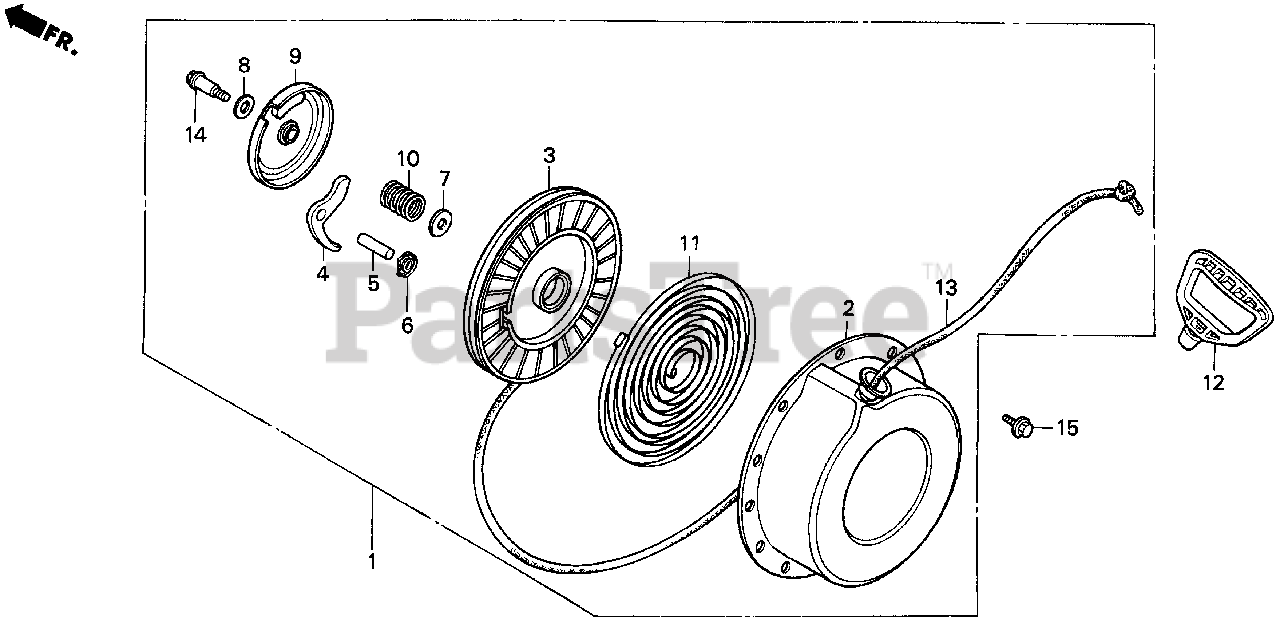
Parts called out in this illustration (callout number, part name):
1	STARTER ASSY., RECOIL *R8* (BRIGHT RED)
2	CASE, STARTER *R8* (BRIGHT RED) (NOT AVAILABLE)
3	REEL, STARTER (NOT AVAILABLE)
4	RATCHET, STARTER
5	SHAFT, RATCHET (NOT AVAILABLE)
6	PLATE, GUIDE
7	PLATE A, FRICTION
8	PLATE B, FRICTION
9	COVER, STARTER REEL
10	SPRING, FRICTION
11	SPRING, RETURN
12	GRIP, STARTER
13	ROPE, STARTER (N/A: USE P/N 08550-ZG921-11)
14	BOLT, REEL COVER
15	BOLT, FLANGE (6X8)
